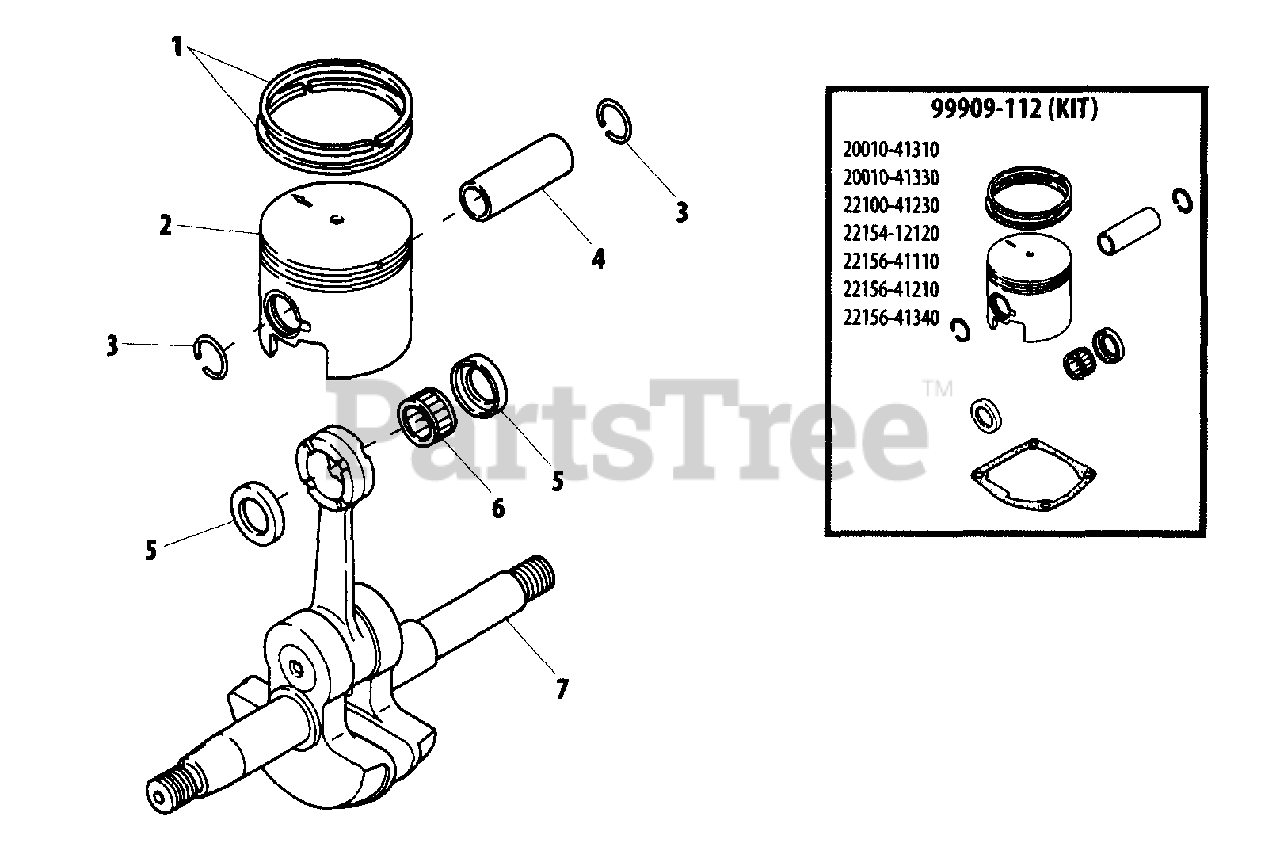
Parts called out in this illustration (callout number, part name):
1	RING, PISTON
2	PISTON
3	RING, SNAP
4	PIN, PISTON 10
5	WASHER, THRUST 10
6	BEARING, NEEDLE 10
7	CRANKSHAFT ASSY
99909-112	PISTON ASSY
